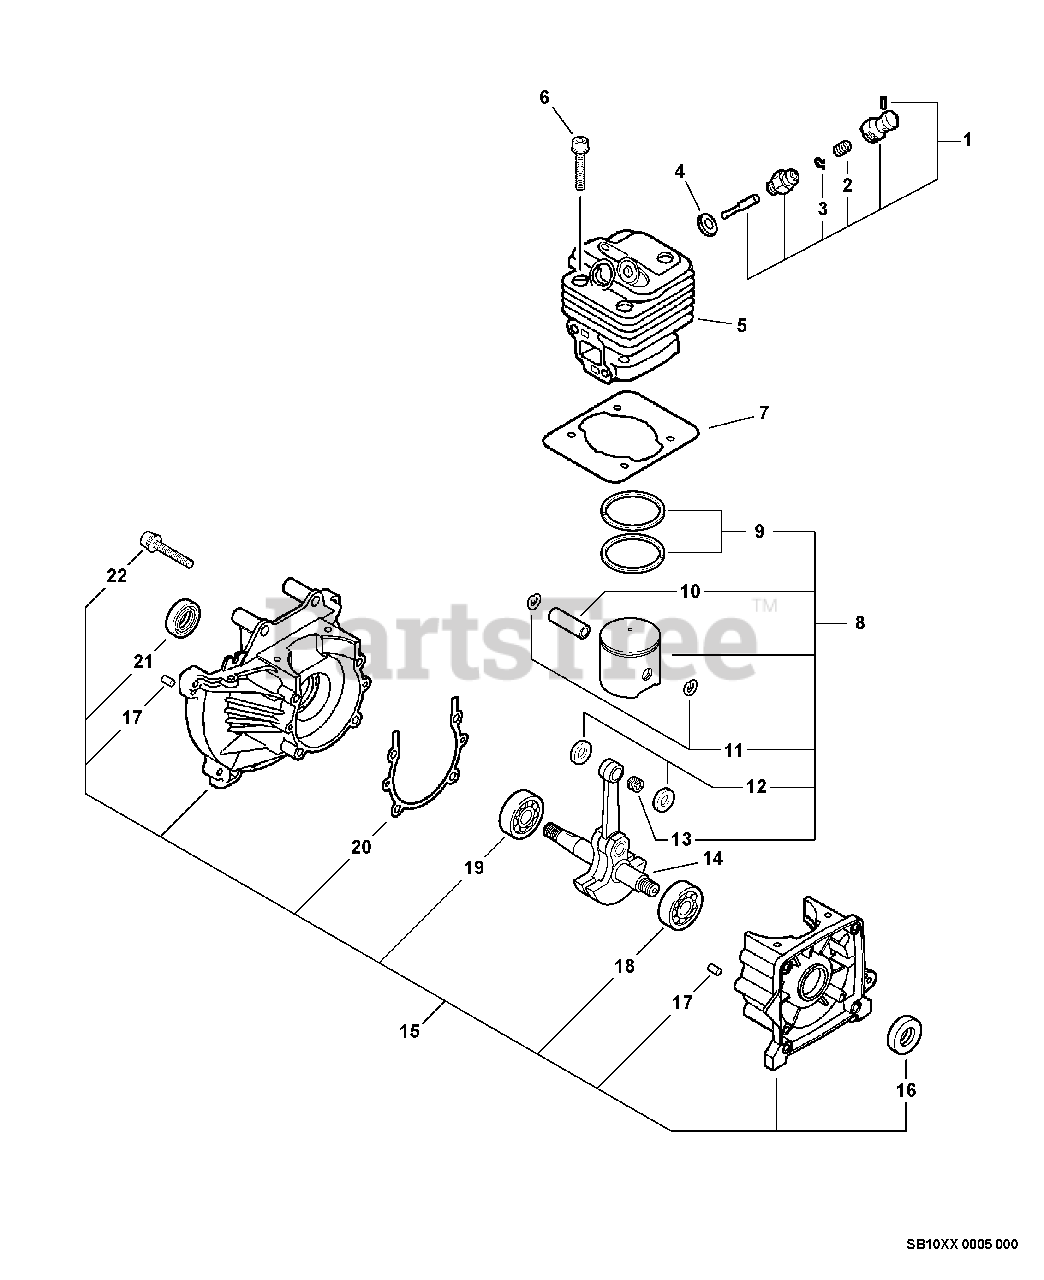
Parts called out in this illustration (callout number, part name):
1	VALVE, DECOMPRESSION
4	GASKET
5	CYLINDER
6	BOLT 5×20
7	GASKET, CYLINDER
8	PISTON KIT
9	RING, PISTON
10	PIN, PISTON 10
11	RING, SNAP 8
12	WASHER, THRUST
13	BEARING, NEEDLE 10
14	CRANKSHAFT ASSY
15	CRANKCASE KIT
16	SEAL, OIL 12
17	PIN, LOCATING 4
18	BEARING, BALL 6202
19	BEARING, BALL - 6201 C3
20	GASKET, CRANKCASE
21	SEAL, OIL
22	BOLT M5×35
